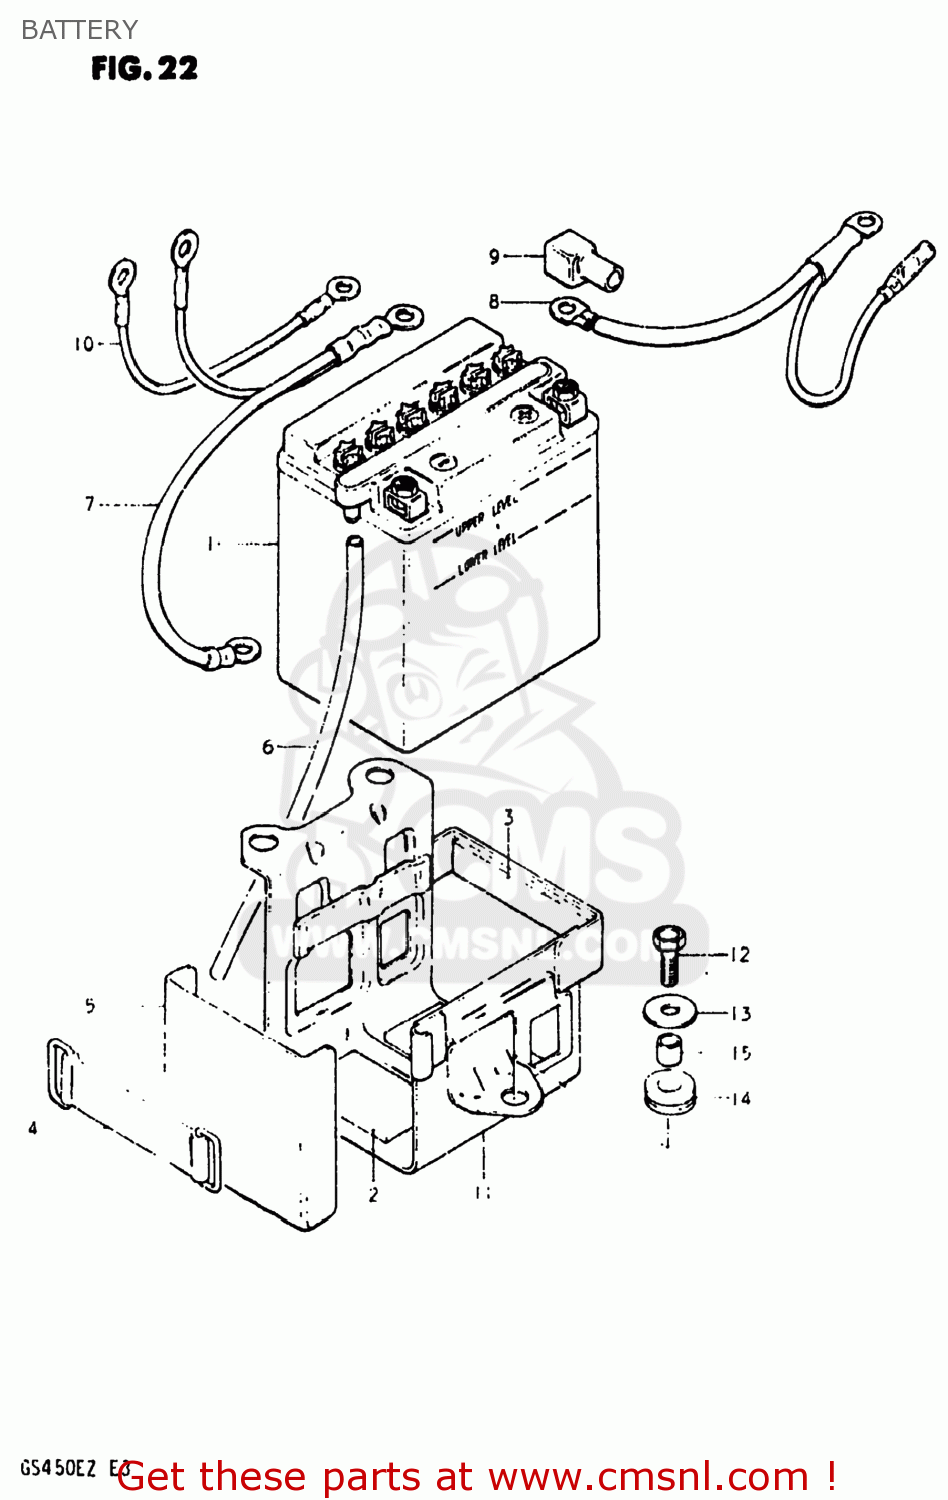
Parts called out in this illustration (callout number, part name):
1	BATTERY ASSY (12V)
2	CUSHION,BATTERY
3	PROTECTOR,20X9
4	BAND
5	COVER,BATTERY
6	HOSE,BATTERY EXHAUST
7	CORD,BATTERY MINUS
8	WIRE,BATTERY PLUS
9	CAP,TERMINAL
10	WIRE
11	HOLDER,BATTERY
12	BOLT
13	WASHER
14	CUSHION
15	SPACER (6.1X9X9)
